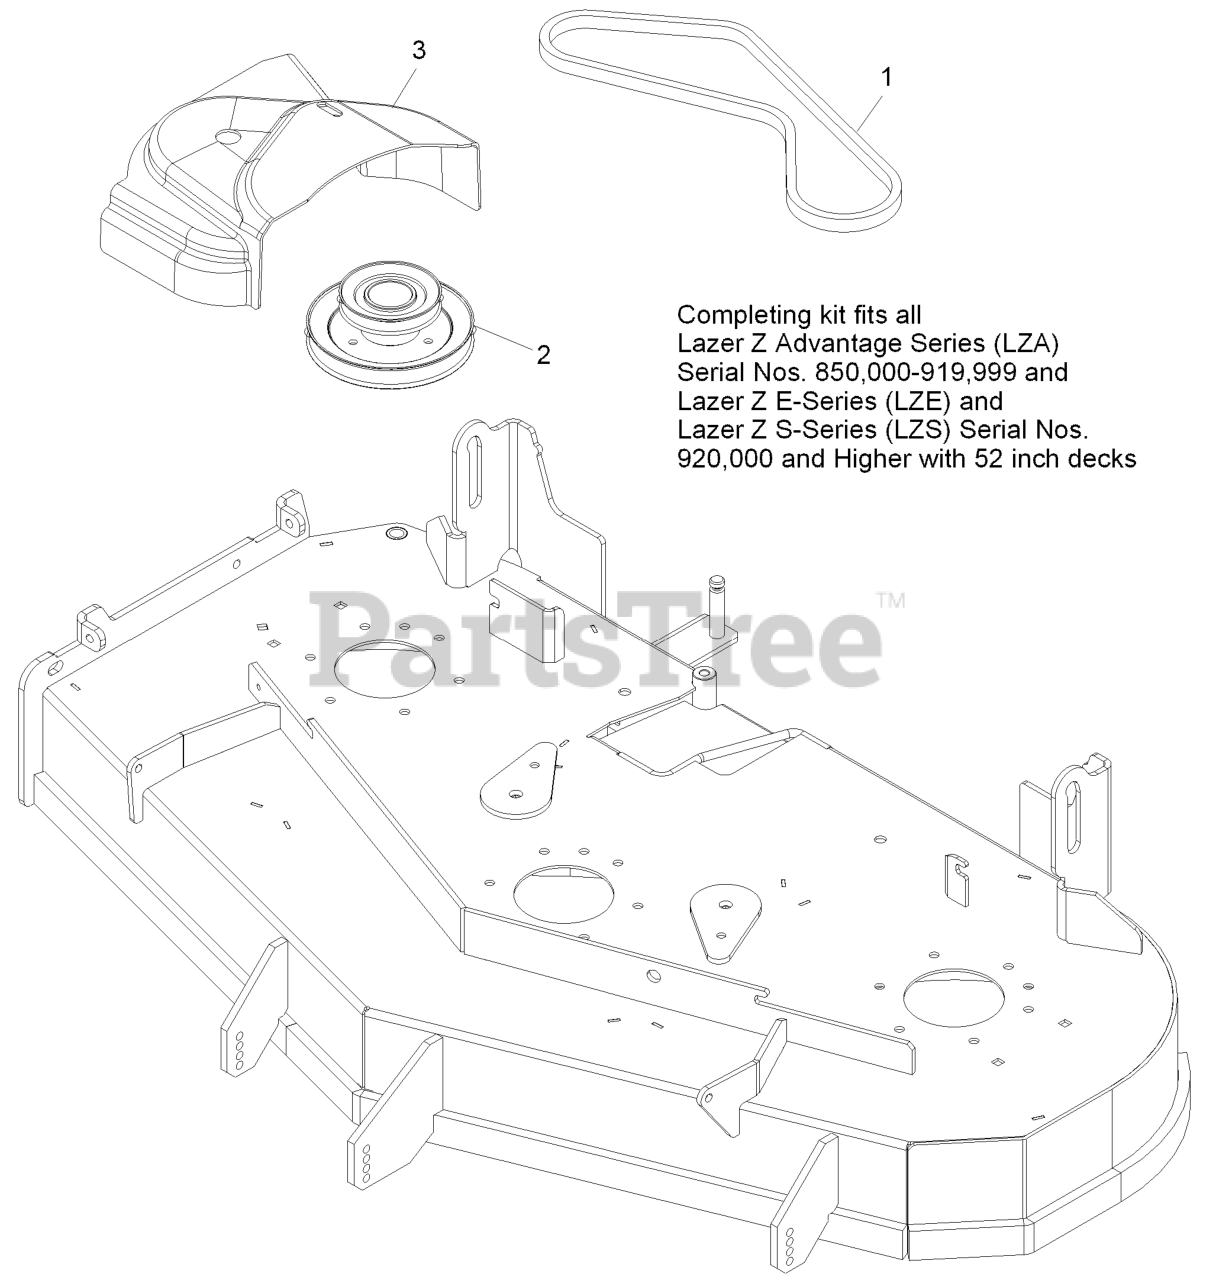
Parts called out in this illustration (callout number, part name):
1	BELT, BLOWER 52"DECK
2	JACKSHAFT,UV DRIVE 524 SP
3	COVER,BELT UV 52
